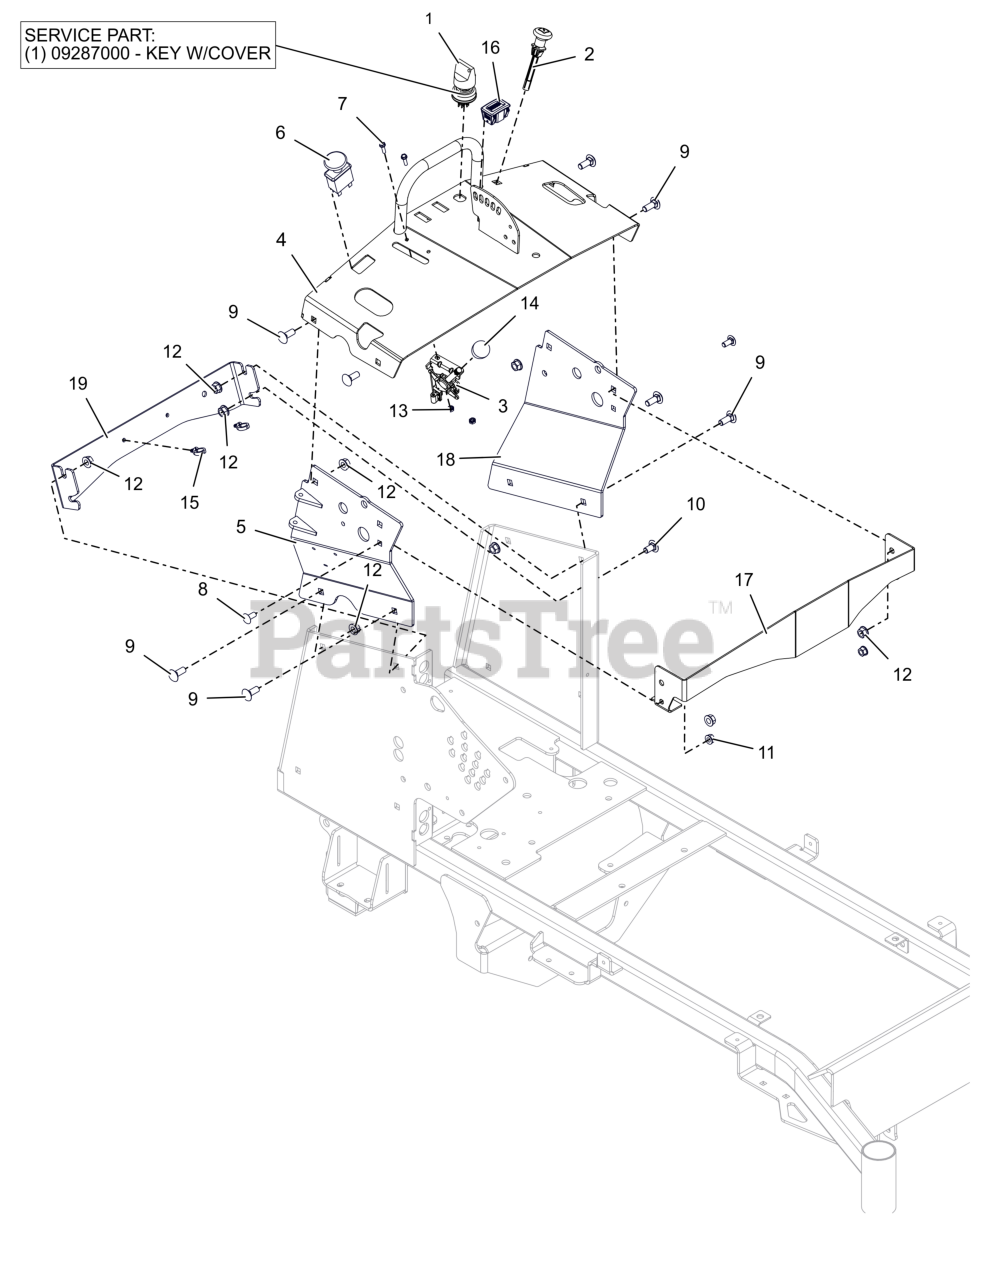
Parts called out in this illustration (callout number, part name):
1	SWITCH, IGNITION
2	CABLE, CHOKE (SNAP IN)
3	CABLE, PRO STANCE - CONTROL 43.00"
4	CONSOLE
5	WLDMT, 32" TOWER RH SUPPORT (ORANGE)
6	SWITCH, CLUTCH
7	BLT, HWH #10-24X.75 ZCC
8	BLT, RHSSN.31-18X.750 G5 ZCC
9	BLT, RHSN .38-16X1.00 G5 ZCC
10	BLT, RHSSN .38-16X.75 G5 ZCC
11	NUT,LK-CTR-FLG .31-18 GF ZCC
12	NUT-LK-CTR-FLG .375-16 GF ZCC
13	NUT, KEPS #10-24 ZCC
14	KNOB-CONTROL-BLACK .38-16X.50
15	CLIP, PUSH-IN X-MAS TREE CABLE
16	METER, HOUR
17	PLATE, DASH ACCENT (BLACK)
18	SUPPORT, 32" TOWER LH (ORANGE)
19	BRKT, DAMPER MOUNT (BLACK)
